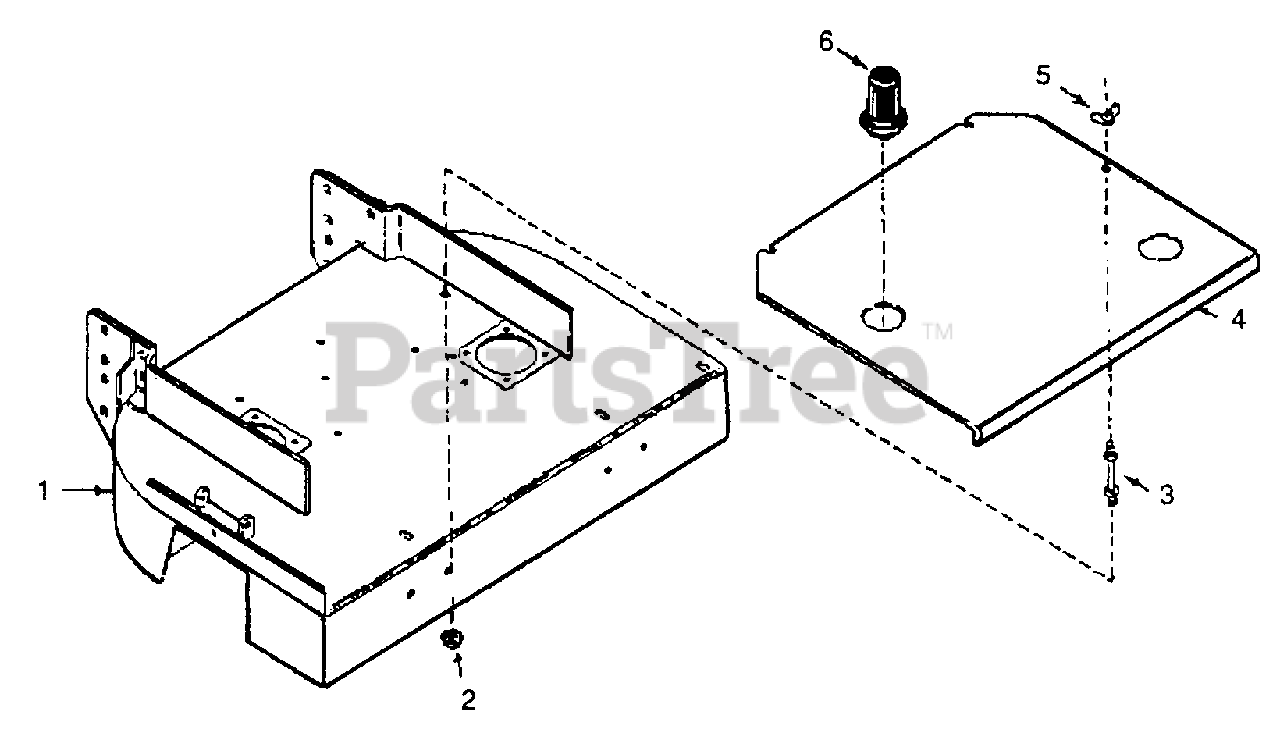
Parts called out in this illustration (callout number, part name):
1	Cutting Deck, 36" W/Decals
2	5/l6" -16 Flange nut
3	Stud, Hood Mount
4	Belt Cover, 36' W/Decals
5	Wing Nut
6	Spindle Guard
